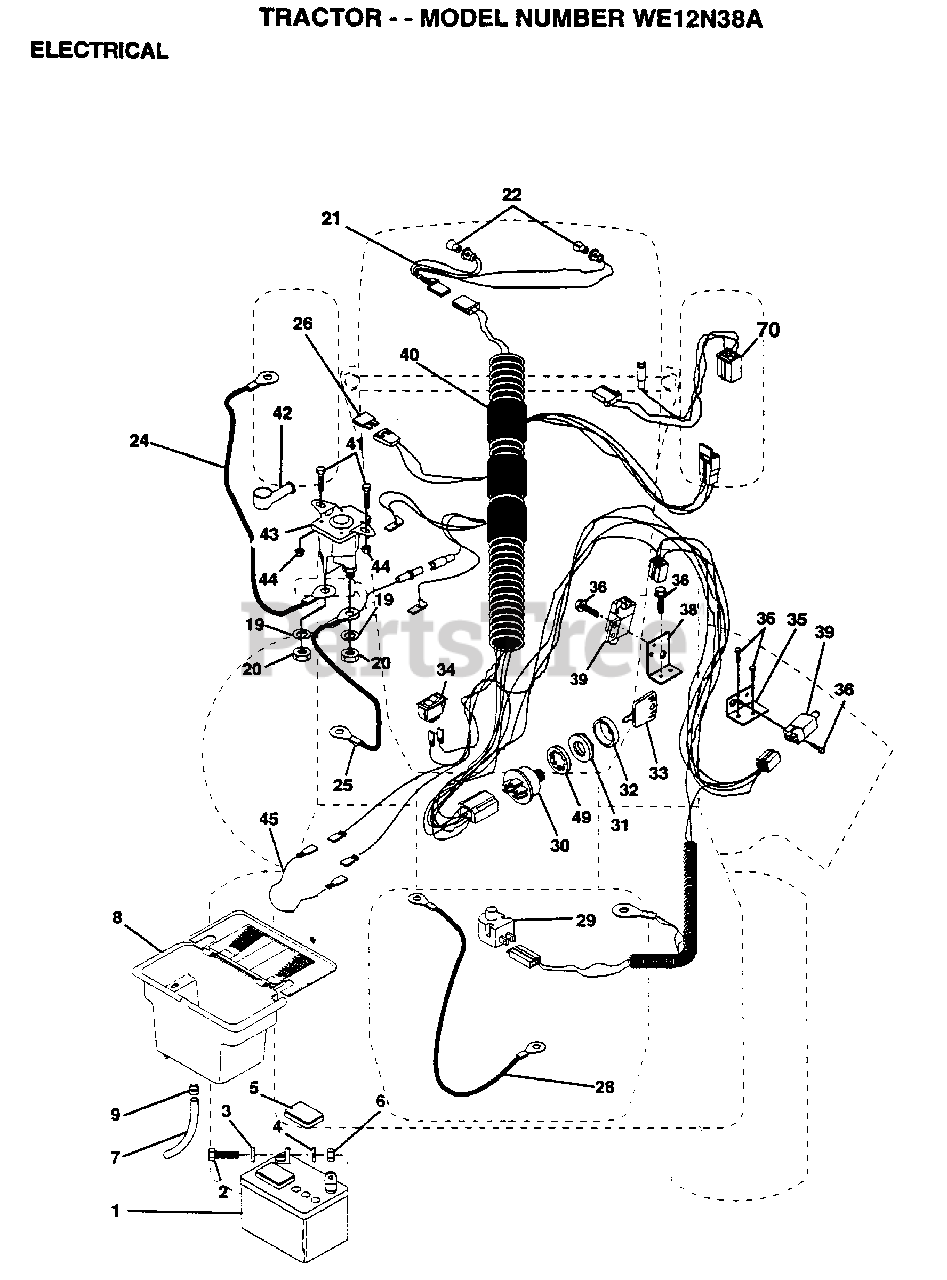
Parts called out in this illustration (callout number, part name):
2	BOLT LT
3	WASHER
4	LOCKWASHER
5	"CAP,BATTERY "
7	TUBE T
9	HOSE CLAMP T
20	NUT
21	"HARNESS,LIGHT SOC"
22	HEADLAMP BULB
24	"CABLE T, BATTERY"
25	CABLE.BTRY.6GA.RD
26	FUSE HYT
28	CABLE T
29	SWITCH SEAT
32	COVER KEY SWITCH
33	KEY MLD GEN DELTA
34	SWITCH LT
35	BRACKET LT
36	SCREW
38	BRACKET SWITCH IN
39	SWITCH INTERLOCKT
40	HARNESS.IGN.DASH.
41	BOLT.HX.1/4-20
44	NUT
45	ADAPTER AMMETER
49	LOCKWASHER
70	HARNESS ENG DUAL
